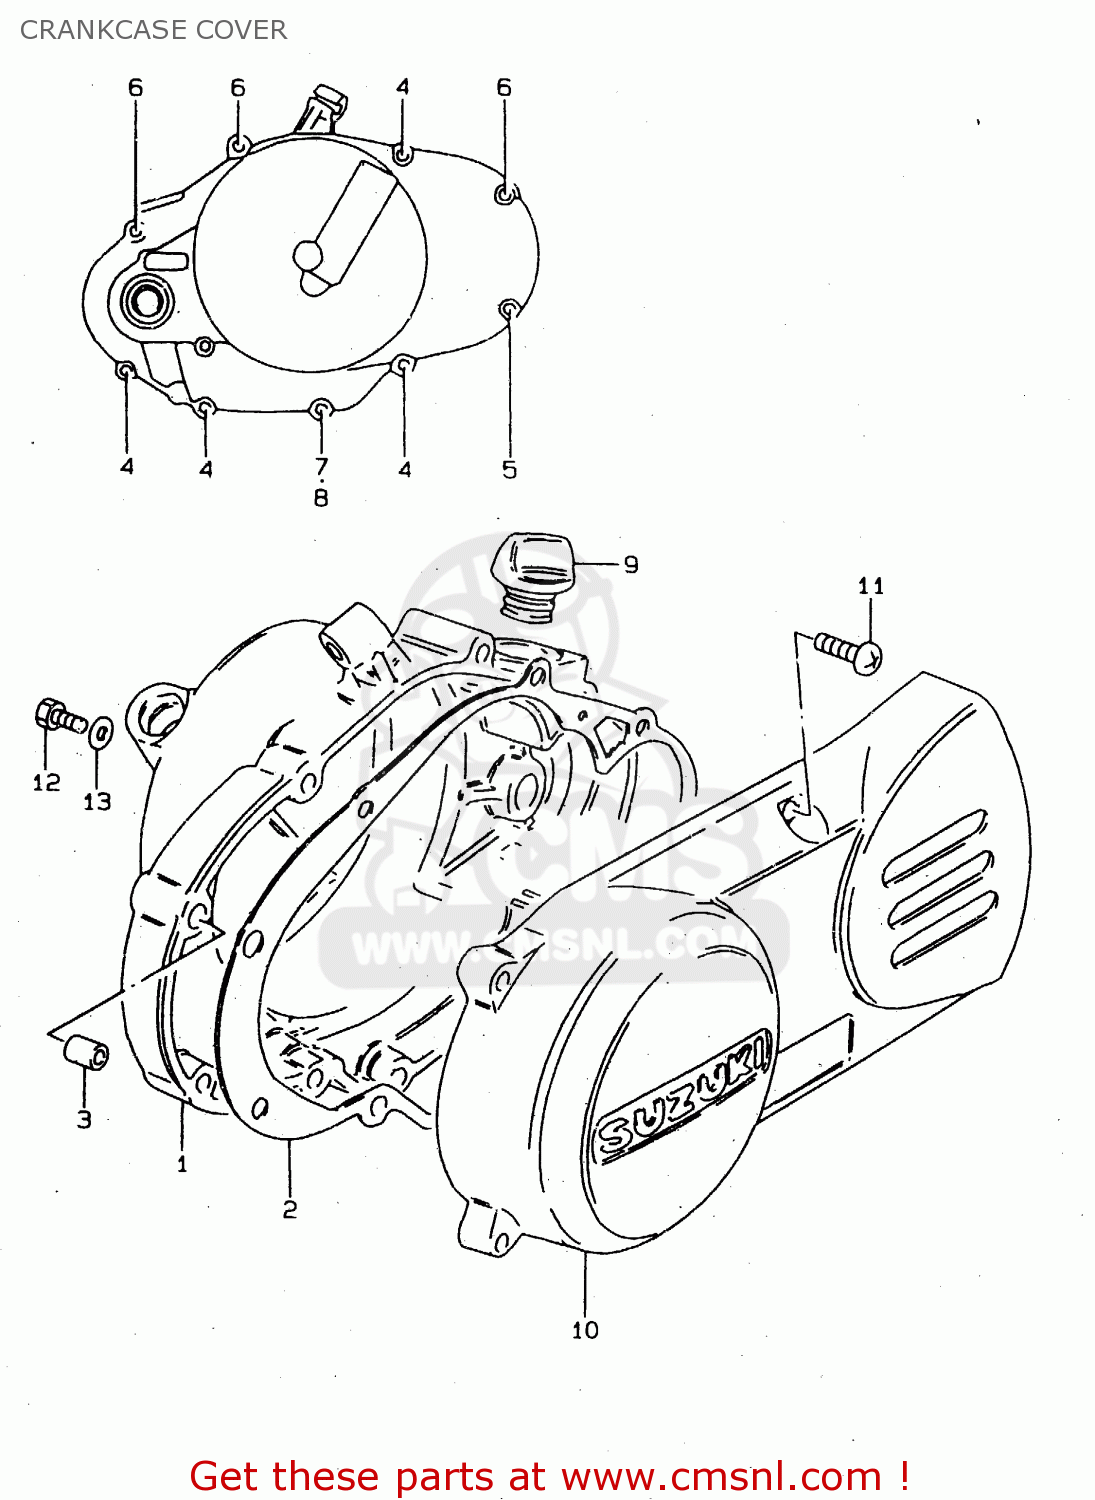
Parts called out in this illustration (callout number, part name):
1	COVER,CLUTCH
2	GASKET,CLUTCH COVER (NAS)
3	PIN
4	SCREW
5	SCREW 6X30
6	SCREW
7	SCREW
8	GASKET(6.2X11X1).2 (NAS)
9	PLUG
10	COVER,MAGNETO
11	SCREW
12	SCREW(6X10)
13	GASKET(6.2X11X1) (NAS)
